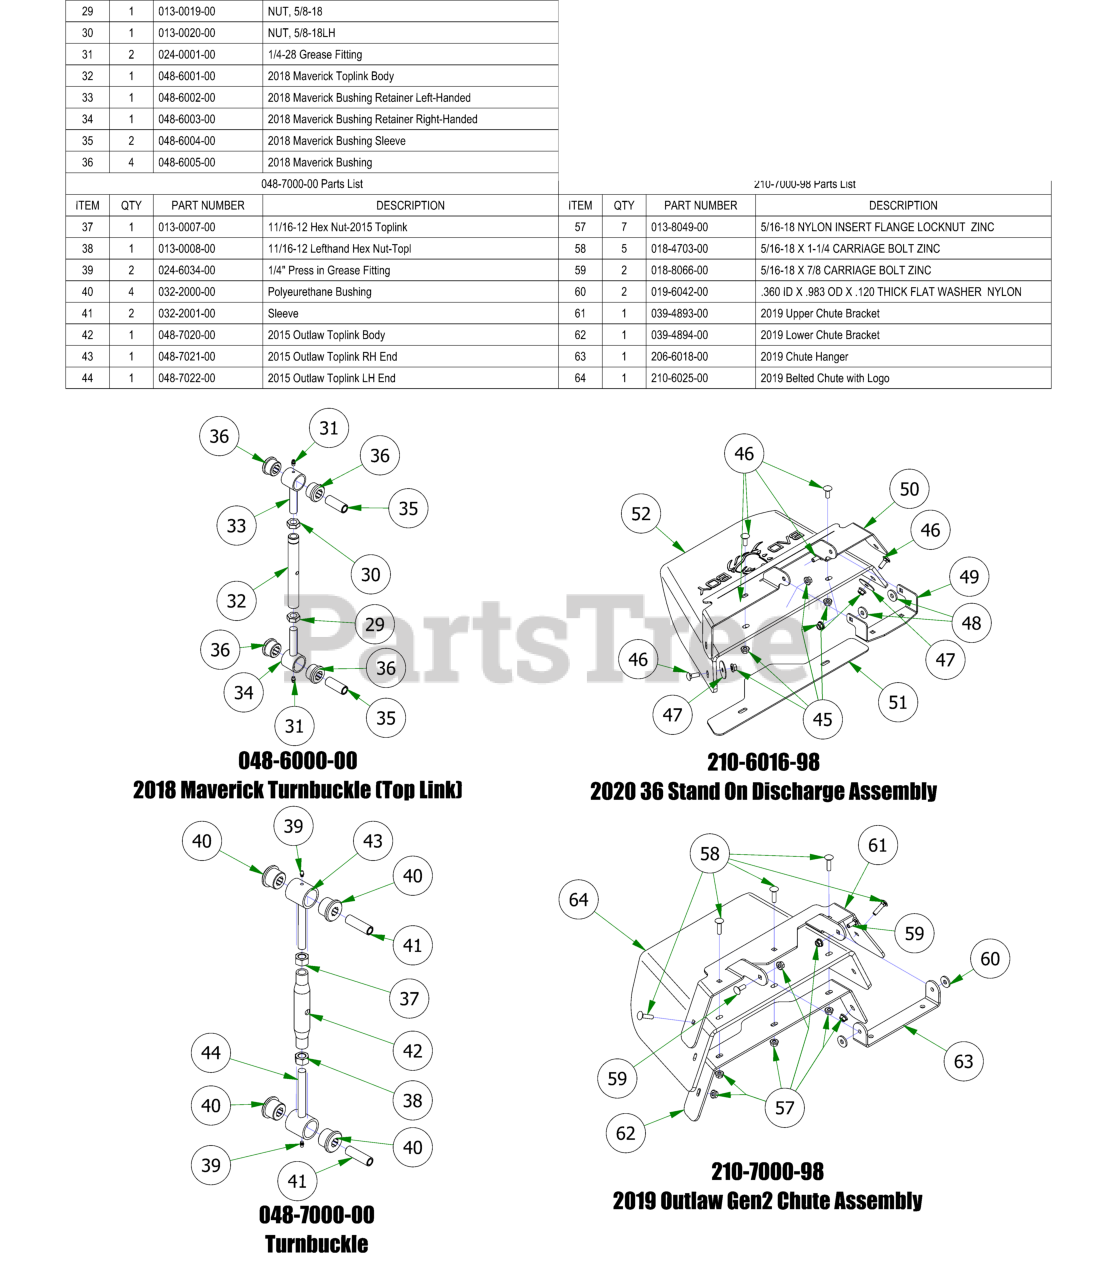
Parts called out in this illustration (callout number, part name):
29	NUT, 5/8-18
30	NUT, 5/8-18LH
31	1/4-28 Grease Fitting
32	2018 Maverick Toplink Body
33	2018 Maverick Bushing Retainer Left-Handed
34	2018 Maverick Bushing Retainer Right-Handed
35	2018 Maverick Bushing Sleeve
36	2018 Maverick Bushing
37	11/16-12 Hex Nut-2015 Toplink
38	11/16-12 Lefthand Hex Nut-Topl
39	1/4" Press in Grease Fitting
40	Polyeurethane Bushing
42	2015 Outlaw Toplink Body
43	2015 Outlaw Toplink RH End
44	2015 Outlaw Toplink LH End
45	5/16-18 NYLON INSERT FLANGE LOCKNUT ZINC
46	5/16-18 X 7/8 CARRIAGE BOLT ZINC
47	5/16 FENDER WASHER (1-1/2 OD) ZINC
48	.360 ID X .983 OD X .120 THICK FLAT WASHER NYLON
49	2020 36 Stand On Chute Hanger
50	Discharge Chute Bracket 48 MZ (Upper)
51	2017 MZ Discharge Chute Bracket-Lower
52	Rubber Discharge Chute MZ (Component)
57	5/16-18 NYLON INSERT FLANGE LOCKNUT ZINC
58	5/16-18 X 1-1/4 CARRIAGE BOLT ZINC
59	5/16-18 X 7/8 CARRIAGE BOLT ZINC
60	.360 ID X .983 OD X .120 THICK FLAT WASHER NYLON
61	2019 Upper Chute Bracket
62	2019 Lower Chute Bracket
63	2019 Chute Hanger
64	2019 Belted Chute with Logo
